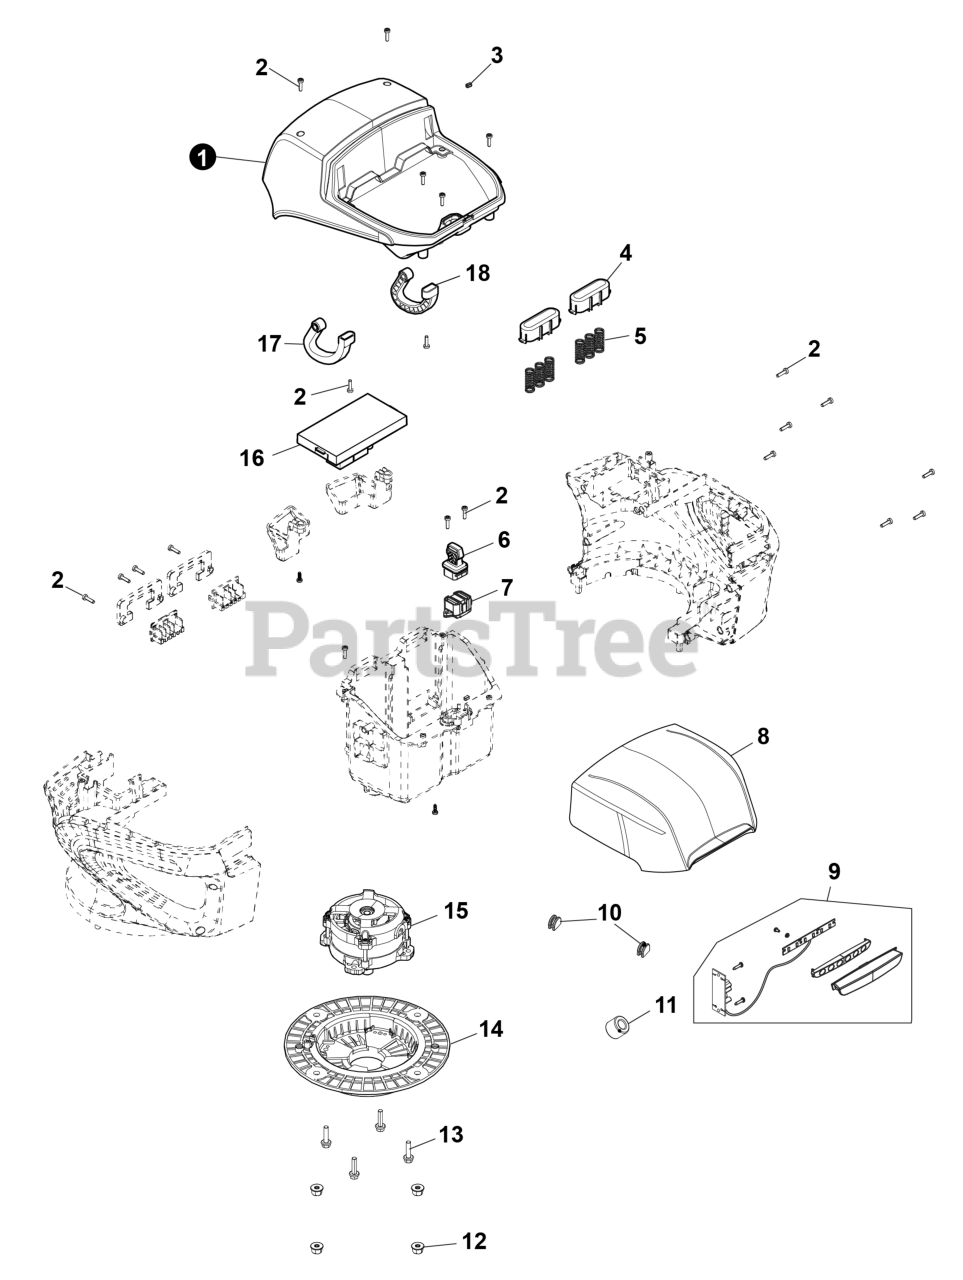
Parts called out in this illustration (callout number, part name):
1	COVER, UPPER
3	PLUG, RUBBER
4	COVER, BATTERY SPRING
7	SWITCH, KEY
8	COVER,BATTERY
9	LIGHT ASSY, LED
10	PLUG,RUBBER
11	RING,MAGNETIC
14	COVER,MOTOR
